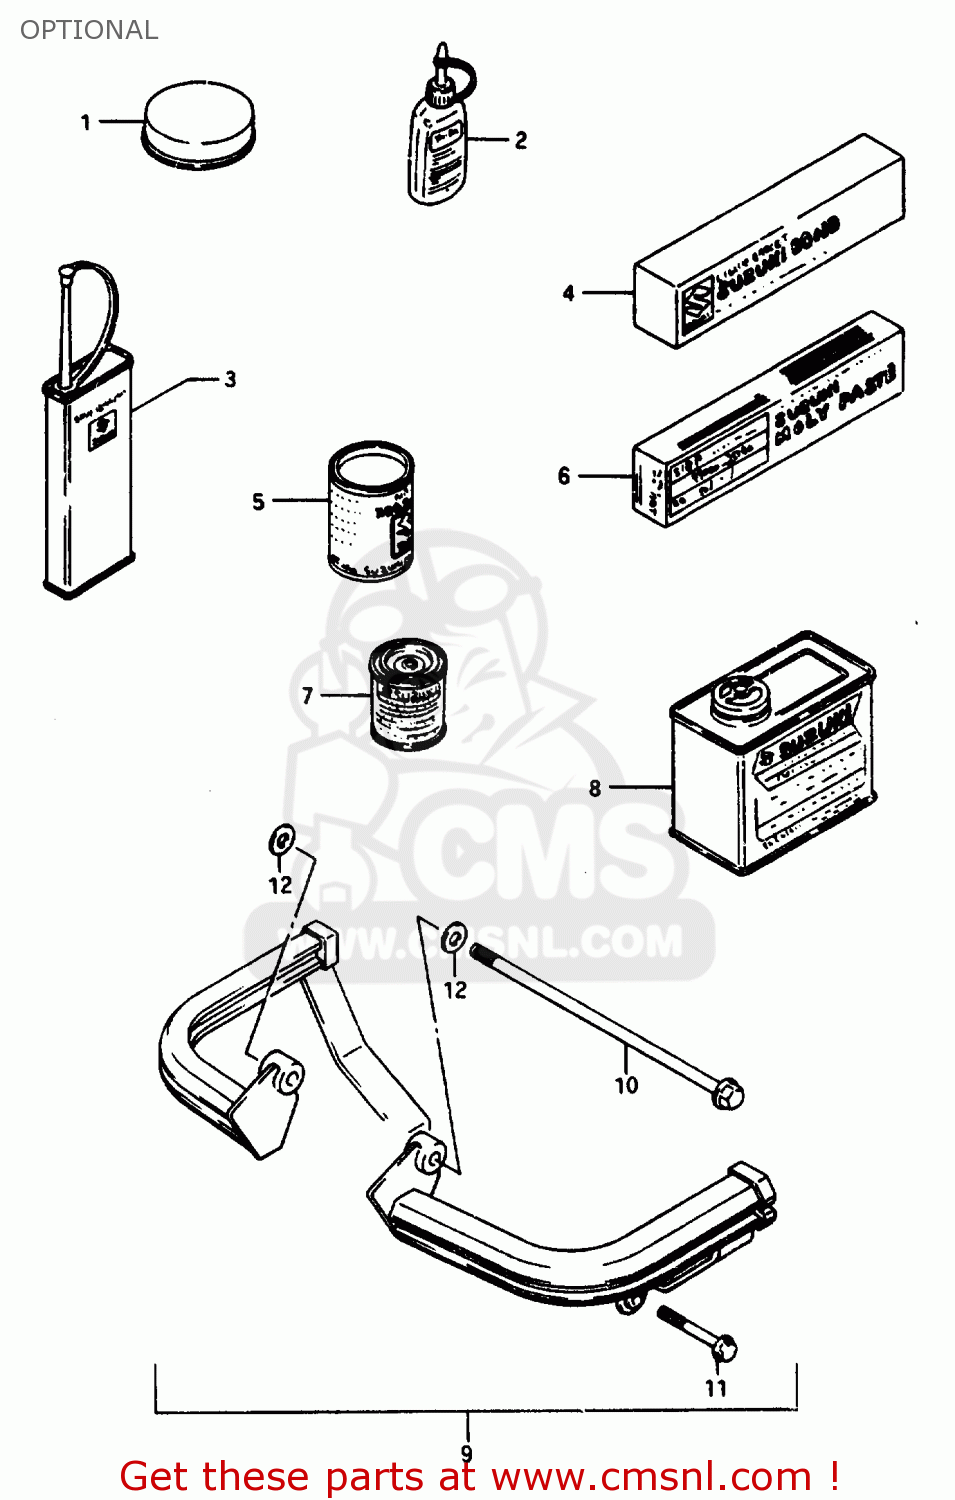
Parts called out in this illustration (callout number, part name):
1	GREASE,PBC FOR BRK PAD 20G
2	THREAD LOCK NO.1342
3	THREAD LOCK NO.1401 CLEAR 200G
4	LIQUID GSKT NO.1207B 100G BLK
5	SUZUKI MOLY PASTE
6	GREASE(C)EP2 LITHIUM 150G
7	PAINT,BLACK
8	PAINT (BLACK)
9	ENGINE CASE GUARD (GSX)
10	BOLT
11	BOLT
12	WASHER
